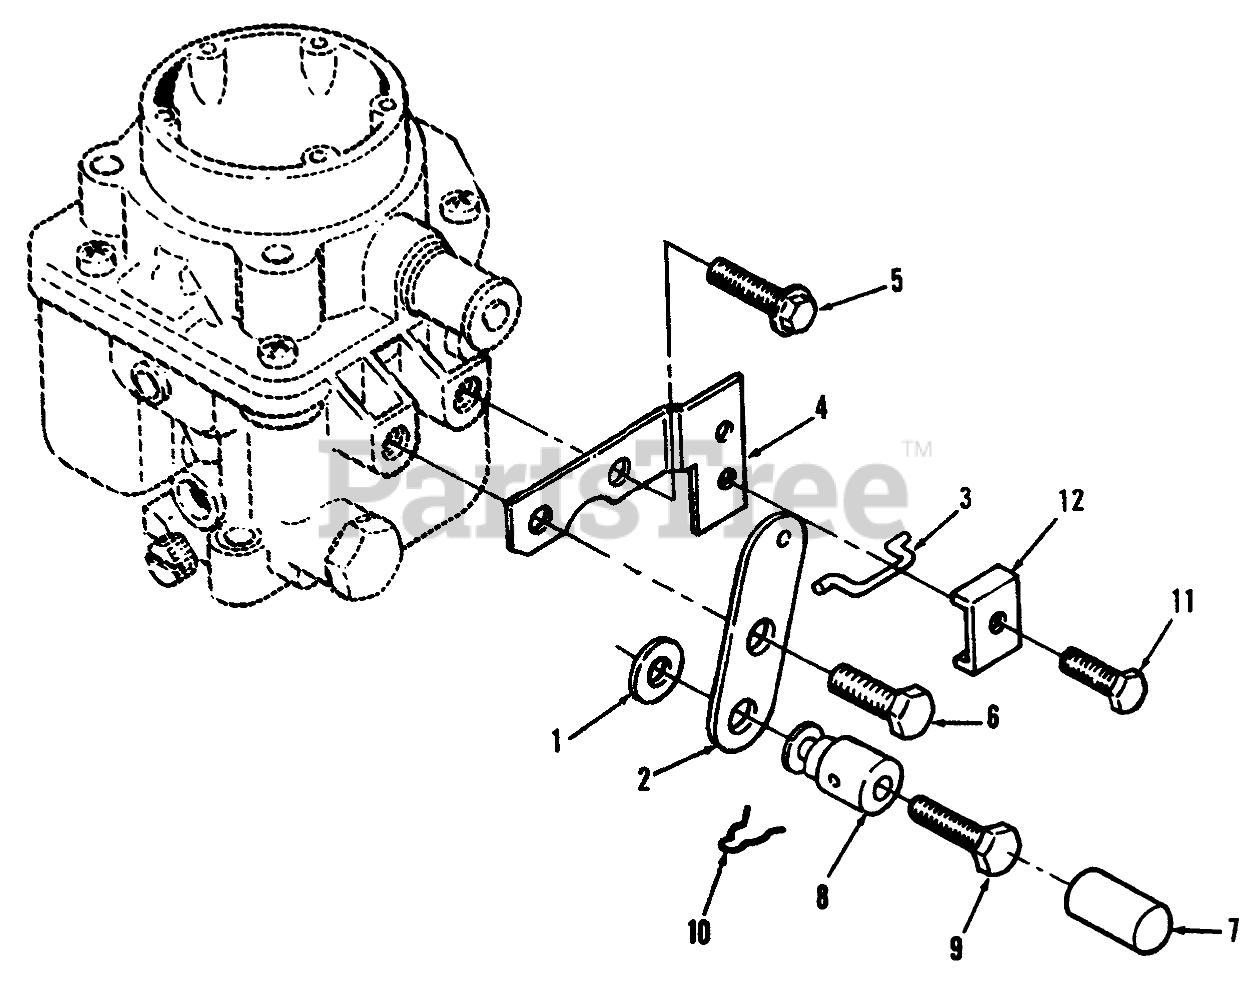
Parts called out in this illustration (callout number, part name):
1	Washer
2	SWIVEL-CHOKE
3	LINK-CHOKE
4	BRACKET
5	Bolt
6	MACHINE SCREW
8	SWIVEL
9	Bolt
10	PIN-COTTER
11	Bolt
